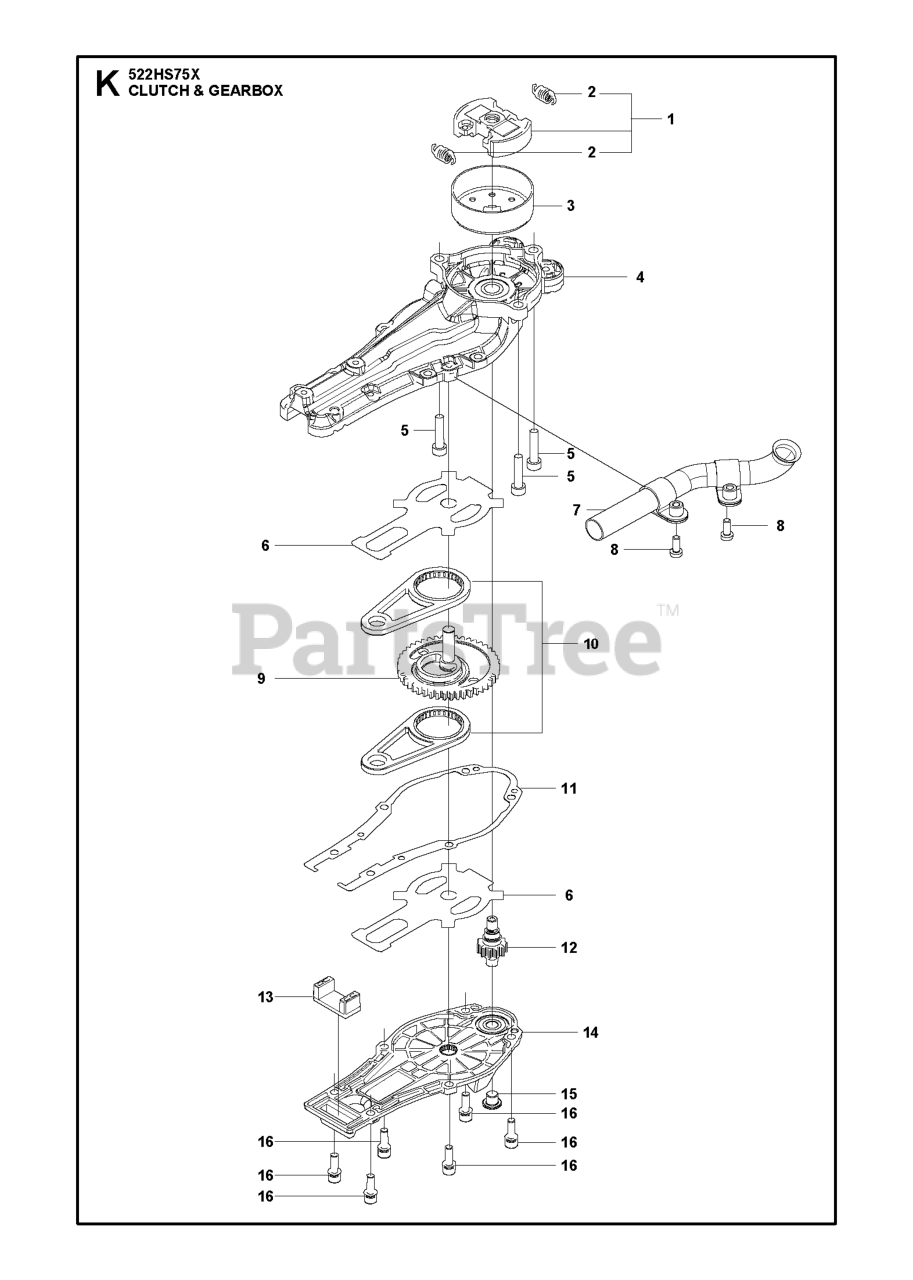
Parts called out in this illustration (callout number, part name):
1	CLUTCH ASSY
2	CLUTCH SPRING CLUTCH SPRING
3	CLUTCH DRUM COPPER BRAZING
4	GEAR HOUSING ASSY KIT UPPER
6	PLATE THRUST
7	EXHAUST PIPE ASSY FOR A051 PRO
9	GEAR WHEEL ASSY
11	GASKET GEAR HOUSING
12	GEAR DRIVE
13	SEALING PLASTIC
14	GEAR HOUSING ASSY KIT LOWER
15	SCREW PLUG HEXALOBULAR SOCKET
